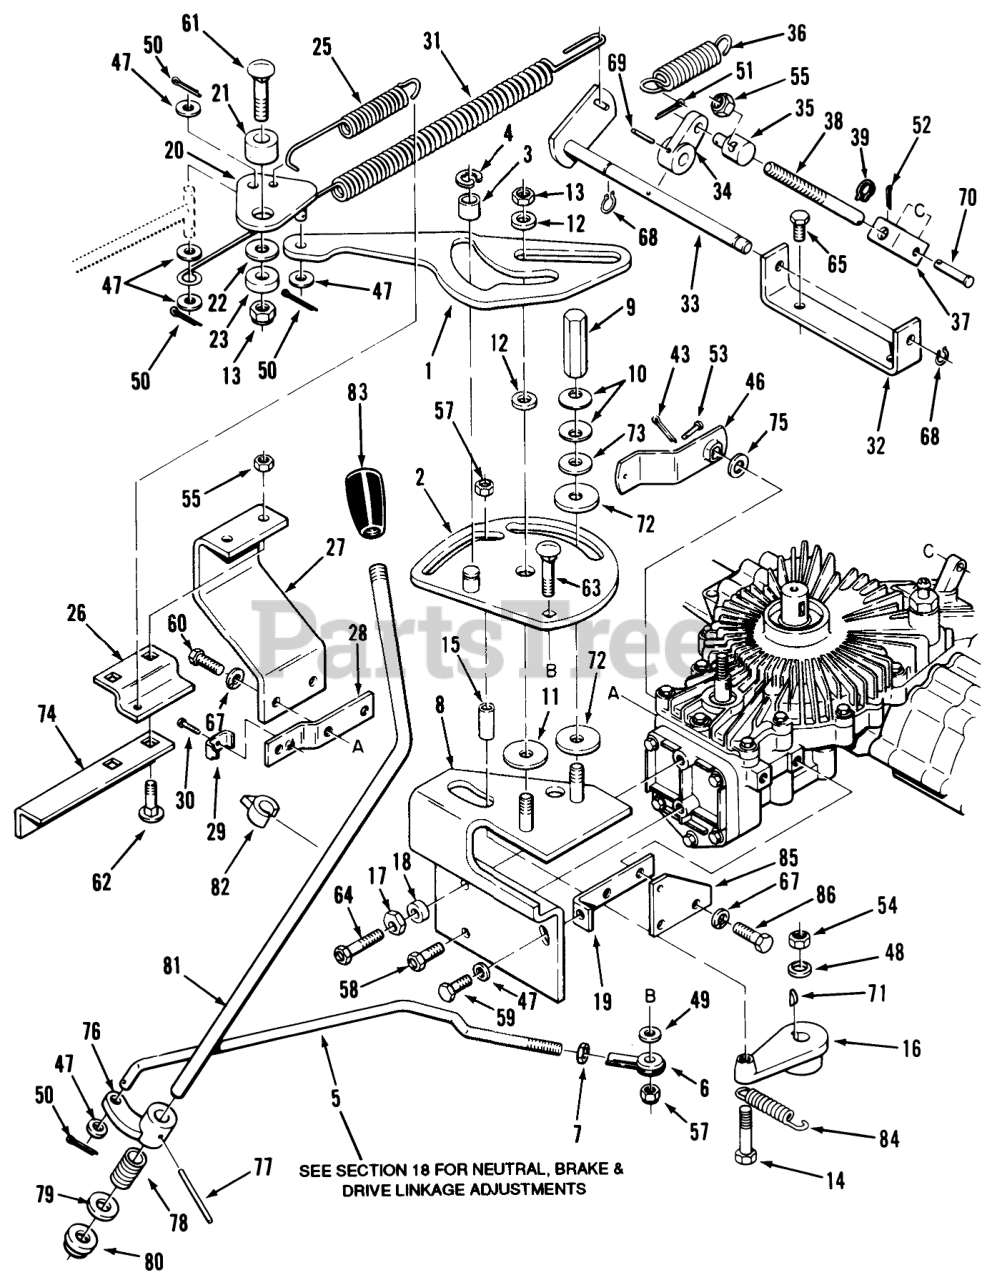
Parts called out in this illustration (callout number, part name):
1	NEUT-RETURN PLATE
2	ASS'Y-CAM PLATE
3	BEARING-CAM RETURN
4	E Ring
5	ROD-SPEED CONTROL
6	ASSY ROD END
7	Jam Nut 1/4-28
8	ASS'Y-CAM PLATE S R
9	NUT-SPECIAL 3/8 X 2"
10	WASHER-SPRING DISC
11	FRICTION WASHER
12	CAM-SPACER
13	NUT-HEX, JAM
14	HHMS 1/4-20 X 2 1/2
15	SPACER
16	ARM MOTION CONTROL
18	SPACER-GEAR
19	ASS'Y-ANGLE SUPPORT
20	PIVOT PLATE ASSY R
21	SPACER
22	WASHER-SPECIAL
23	SPACER-LIFT LINK
25	SPRING-RETURN
26	BRACKET R
27	BRACKET-TORQUE R
28	PLATE-MOUNTING R
29	CLAMP THROTTLE
30	HWHTRS 10-24 X 1/2
31	SPRING-BRAKE
32	BRACKET
33	ASS'Y-BRAKE PIVOT
34	PLATE
35	TRUNNION-CLUTCH ROD
36	SPRING-BRAKE
37	CLEVIS R
38	BOLT-ADJUSTING
39	E-Ring
43	Cotter Pin
46	PLATE-ARM
47	WASHER 5/16 SAE
48	Washer
50	Cotter Pin
51	Cotter Pin
52	Cotter Pin
54	Nut
55	Nut
57	Nut
58	Screw
59	Bolt
60	Bolt
61	Bolt
62	Bolt-Carriage
63	Carriage Bolt 1/4-20 x 1
64	Bolt
65	Bolt
67	Lockwasher
68	EXTERNAL SNAP RING
69	Pin-Roll
71	KEY WOODR 1/8X1/2 DI
72	WASHER-FRICTION
73	Washer
74	BRACKET R
75	Washer
76	ARM SHIFTER B
77	SPIROL PIN 7/32X21/2
78	SPRING COMPRESSION
79	Washer
80	BUSHING-NYLINER
81	ROD-SHIFT LEVER
82	POINTER
84	SPRING
85	BRACKET-SPRING
86	Bolt
